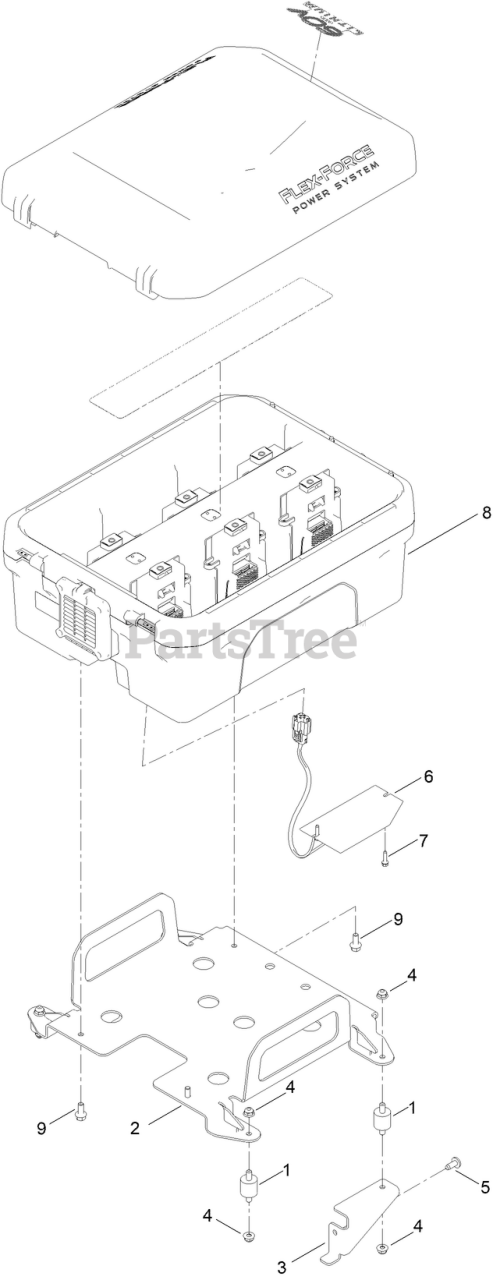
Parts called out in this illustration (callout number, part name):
1	ISOLATOR-1 IN OD (5/16-18)
2	BATTERY MOUNT ASM [RED]
3	MOUNT-BOX, REAR
4	NUT-HF
6	RESISTOR-REGEN
7	SCREW-HWH THD ROLL
8	BOX-BATTERY, ASM
9	SCREW-HHF
